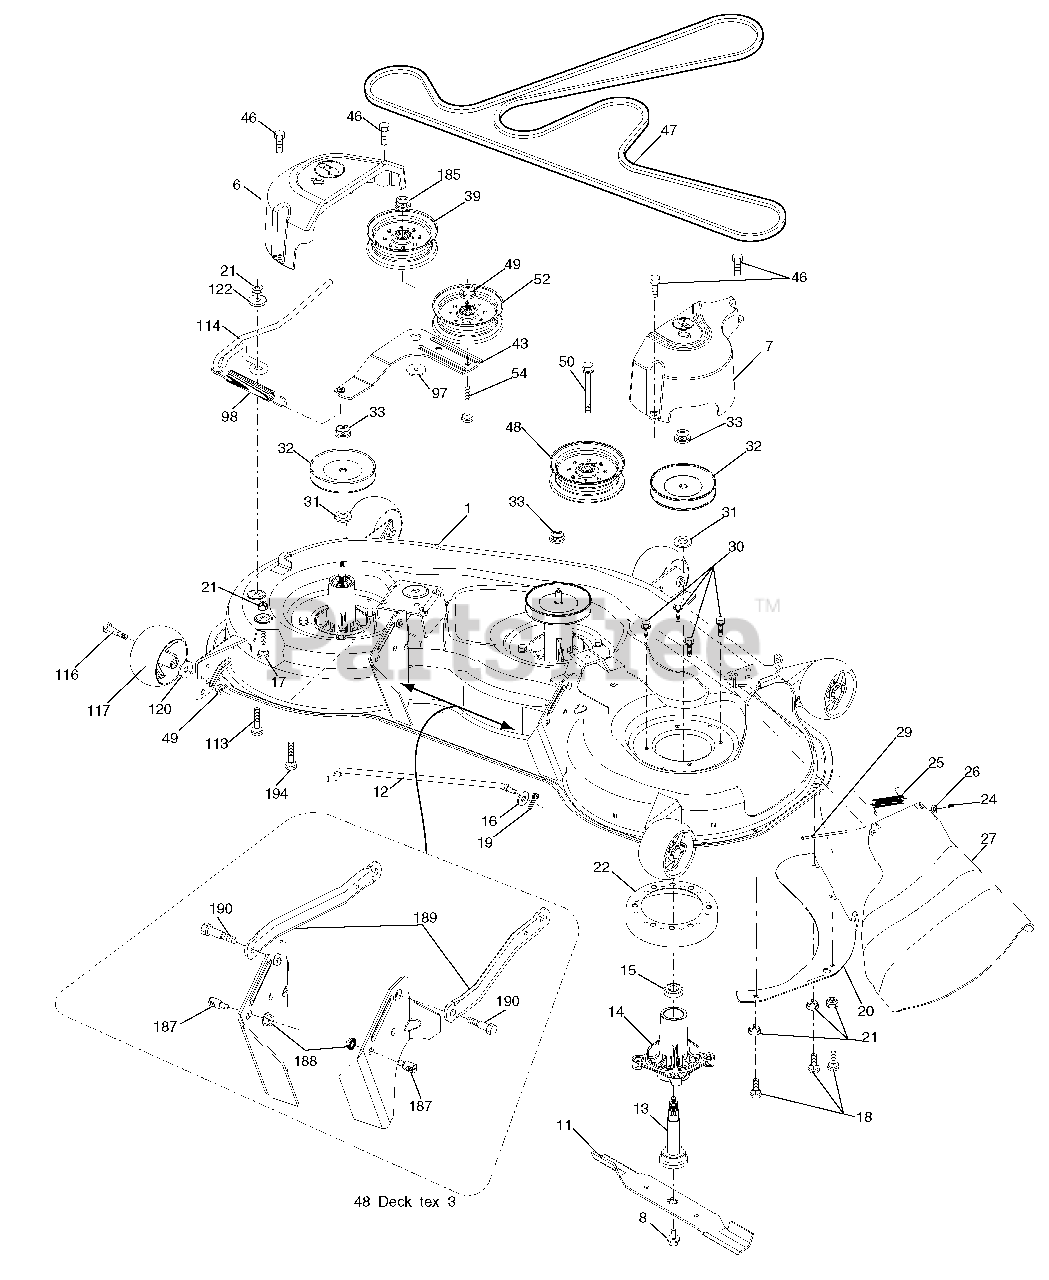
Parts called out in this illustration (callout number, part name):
1	Deck Weldment Mower
6	Cover Mandrel LH
7	Cover Mandrel RH
8	Bolt 7/16 Asm. Blade
11	Blade High Lift
12	Rod Anti Sway
13	Shaft Asm. w/Lower Bearing
14	Housing, Mandrel
15	Bearing, Ball, Mandrel
16	Washer 3/8
17	Bolt Carriage 5/16-18 x 5/8
18	Bolt RdHd 5/16-18 unc x 5/8
19	Pin Cotter 5/16 Bowtie
20	Baffle Vortex Mower
21	Nut, Crownlock 5/16-18 unc
22	Stripper Mandrel Deck
24	Cap Sleeve
25	Spring, Torsion
27	Deflector Shield
29	Rod, Hinge
30	Screw, Thdroll Washer Head
31	Washer, Spacer Mower Vented
32	Pulley, Mandrel
33	Nut, Flg. Top Lock
39	Pulley, Idler, Stationary LH
43	Arm, Idler
46	Screw, Thdroll. 1/4-20 x 5/8
47	Belt Deck Drive
48	Pulley Idler
49	Nut, Lock Flg. 3/8-16 unc
50	Bolt Carriage 3/8-16 x 1-1/2 Gr. 5
52	Pulley Idler Clutching
54	Screw 3/8-16 x 2-1/4
97	Washer Hardened
98	Spring Drive
113	Bolt Rdhd Sqnk 5/16-18 x 3/4
114	Rod Tension Relief
116	Bolt, Shoulder
117	Gauge Wheel
120	Washer 13/32 x 1-1/4 x 12 Ga.
122	Bushing Tension Relief
185	Nut Lock Flange 7/16-14 Gr. 5
187	Stud Fastener w/"D" Anti-Rotation
188	Nut Lock Hex Flange
189	Arm Susp. Mower Rear
190	Bolt Shoulder
194	Bolt Carr Sqnk 7/16-24 x 2
194	Mandrel Asm. Service
194	Replacement Mower, Complete
